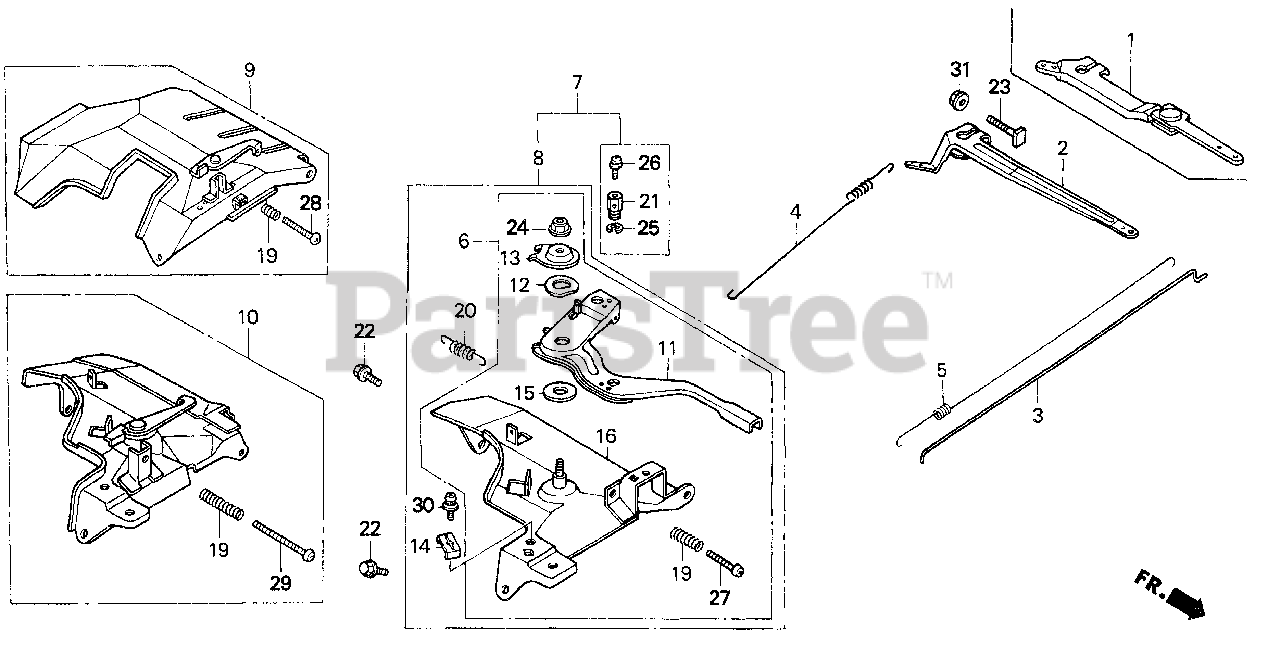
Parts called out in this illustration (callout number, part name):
2	ARM, GOVERNOR
3	ROD, GOVERNOR
4	SPRING, GOVERNOR
5	SPRING, THROTTLE RETURN
8	CONTROL ASSY. (REMOTE)
11	LEVER, CONTROL
12	SPRING, LEVER
13	WASHER, CONTROL LEVER
14	HOLDER, CABLE
15	SPACER, CONTROL LEVER
16	BASE, CONTROL
19	SPRING, CONTROL ADJUSTING
20	SPRING, CABLE RETURN
22	BOLT, FLANGE (6X12) (CT200)
23	BOLT, GOVERNOR ARM
24	NUT, SELF-LOCK (6MM)
27	SCREW, PAN (5X32)
30	SCREW, PAN (5X16)
30	SCREW-WASHER (5X16)
31	NUT, FLANGE (6MM)
